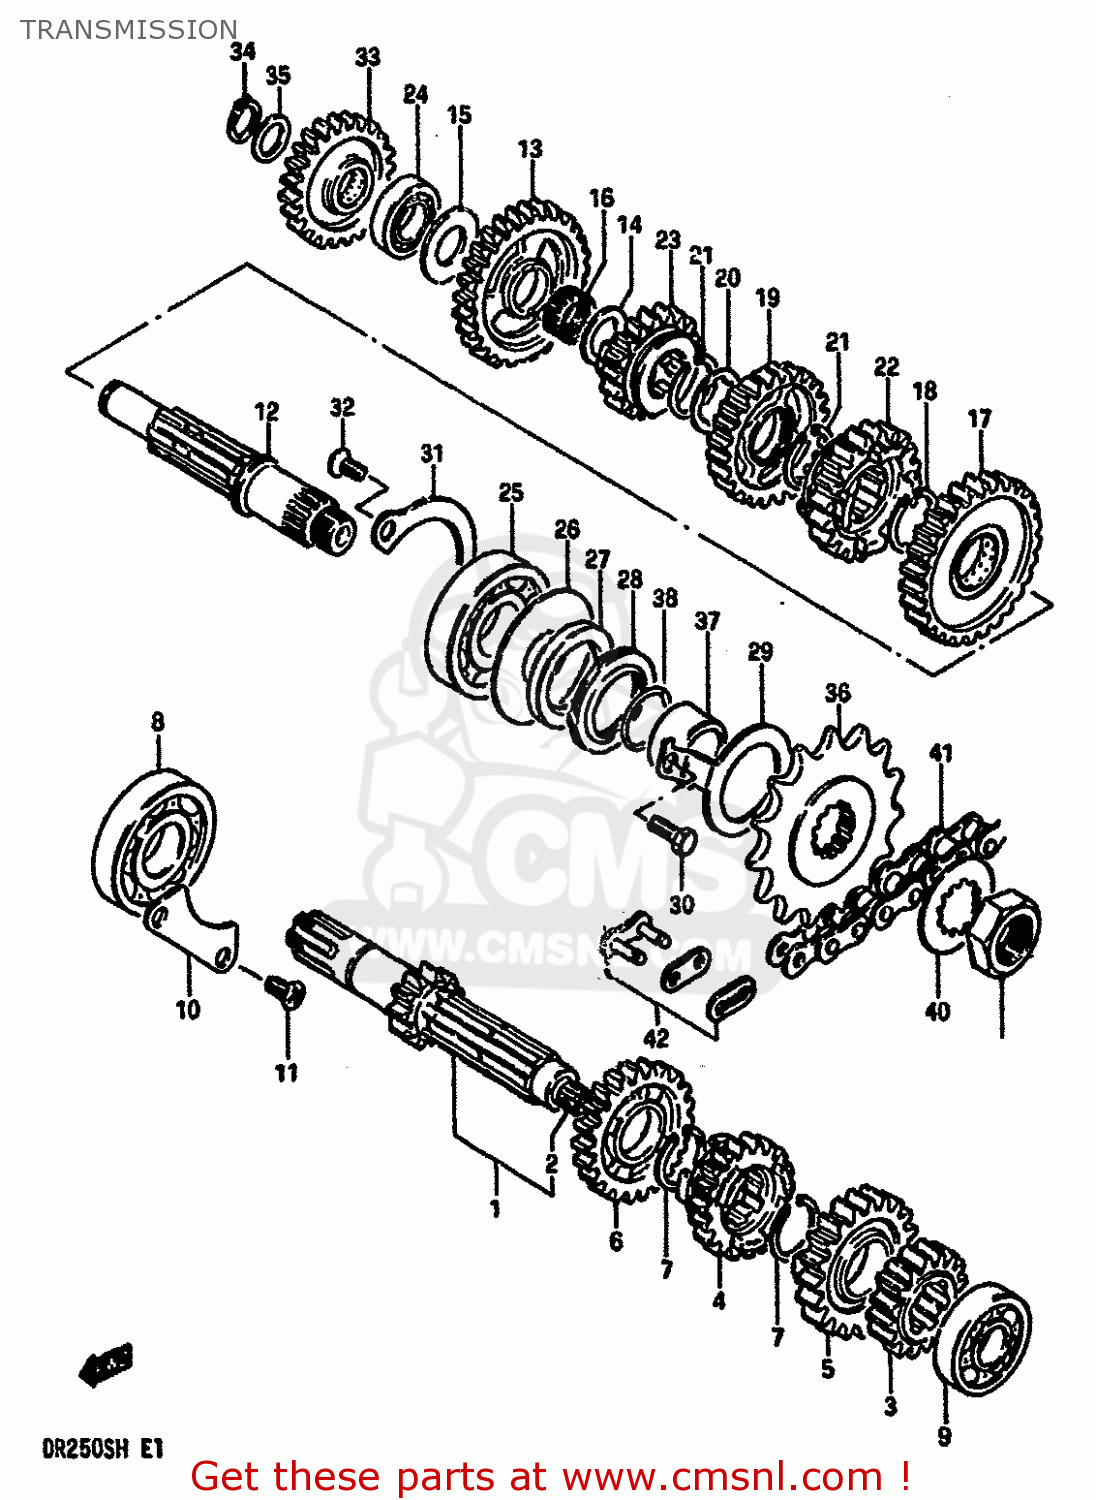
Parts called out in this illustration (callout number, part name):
1	SHAFT,COUNTER
2	BUSH
3	GEAR,2ND DRIVE(NT:16)
4	GEAR,THIRD DRIVE (NT:19)
5	GEAR,FOURTH DRIVE
6	GEAR,FIFTH DRIVE
7	CIRCLIP
8	BEARING
9	BEARING
10	RETAINER,CNTR SHAFT BEARING
11	SCREW 6X12
12	SHAFT,DRIVE
13	GEAR,1ST DRIVEN(NT:29)
14	WASHER
15	WASHER
16	BEARING(17X21X9.8)
17	GEAR,2ND DRIVEN(NT:27)
18	CIRCLIP
19	GEAR,THIRD DRIVEN
20	WASHER,LOCK
21	CIRCLIP
22	GEAR,FOURTH DRIVEN
23	GEAR,FIFTH DRIVEN
24	BEARING(17X36X12)
25	BEARING(22X56X16)
26	WASHER(35X55X1)
27	OIL SEAL (30X43X5)
28	OIL SEAL (30X43X7)
29	RETAINER,DRIVE SHAFT OIL SEAL
30	BOLT
31	RETAINER,DRIVE SHAFT BEARING
32	SCREW
33	GEAR,KICK STARTER IDLE(NT:24)
34	CIRCLIP
35	WASHER
36	SPROCKET,ENGINE(NT:15)
37	SPACER,ENGINE SPROCKET
38	O RING(D:2.5,ID:21)
39	NUT
40	WASHER,LOCK
41	CHAIN ASSEMBLY,DRIVE
42	JOINT ASSEMBLY,CHAIN
